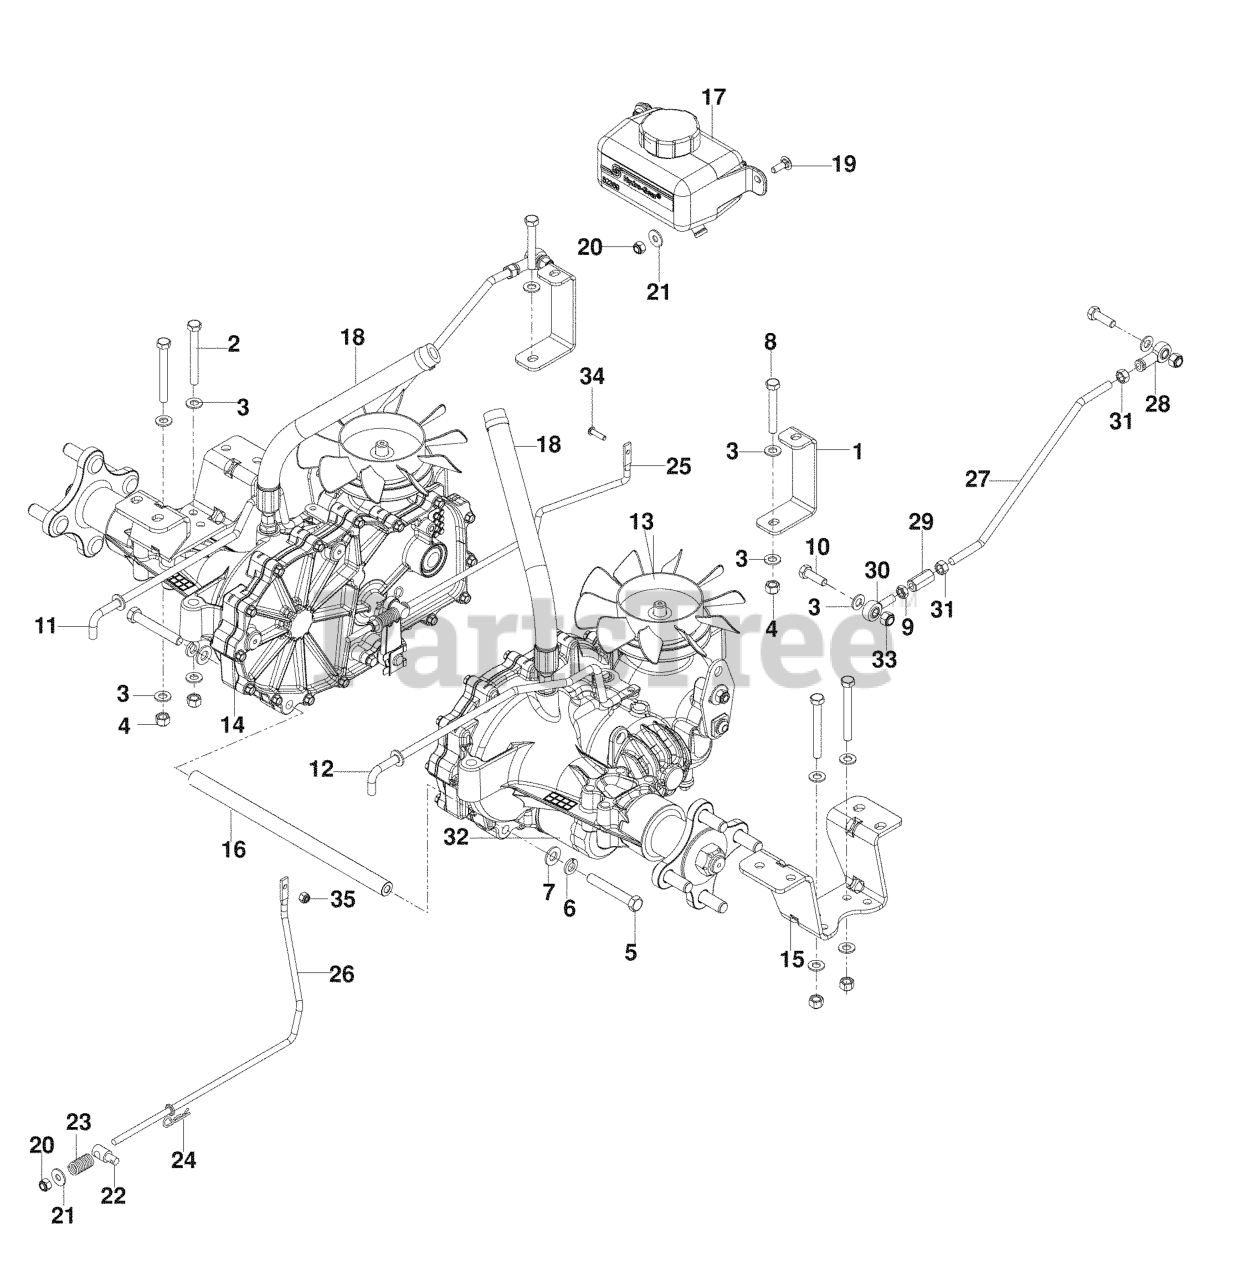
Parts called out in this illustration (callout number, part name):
1	SUPPORT.FRONT.TRANS.BLACK.
2	HCS 5/16C X 2-3/4
3	FLAT WASHER 5/16 SAE
4	NUT 5/16 NYLOC
5	HCS 3/8C X 2 1/2
6	SLW 3/8 STD
7	WASHER 3/8 SAE FLAT
9	NUT 5/16F LEFTHAND
10	HCS 5/16C X 1
11	ROD, BYPASS, RT
12	ROD, BYPASS, LT
13	HG_TRANS, ZT-2800 RT
14	HG_TRANS, ZT-2800 LEFT
15	EZT MOUNT, REAR, BLACK
16	SPACER TUBE, EZT, 11.08
17	HG_EXPANSION TANK W/CAP 71354
19	RHSNB 1/4C X 3/4
20	NUT.1/4-20.HEX.NYLOC.ZD
21	WASHER 1/4 FLAT
22	BRAKE SWIVEL
24	HAIRPIN #2
25	LINKAGE.BRAKE.LT
26	LINKAGE, BRAKE RT
27	ROD, MOTION CONTROL
28	RH ROD END
29	ROD END COUPLER
30	RP.ROD.END.LH
32	HG_FILTER, ZT4800 52114
33	5/16-18 THIN PROF NY
34	SCR #10-24 X 3/4
35	NUT 10-24 NYLOC
